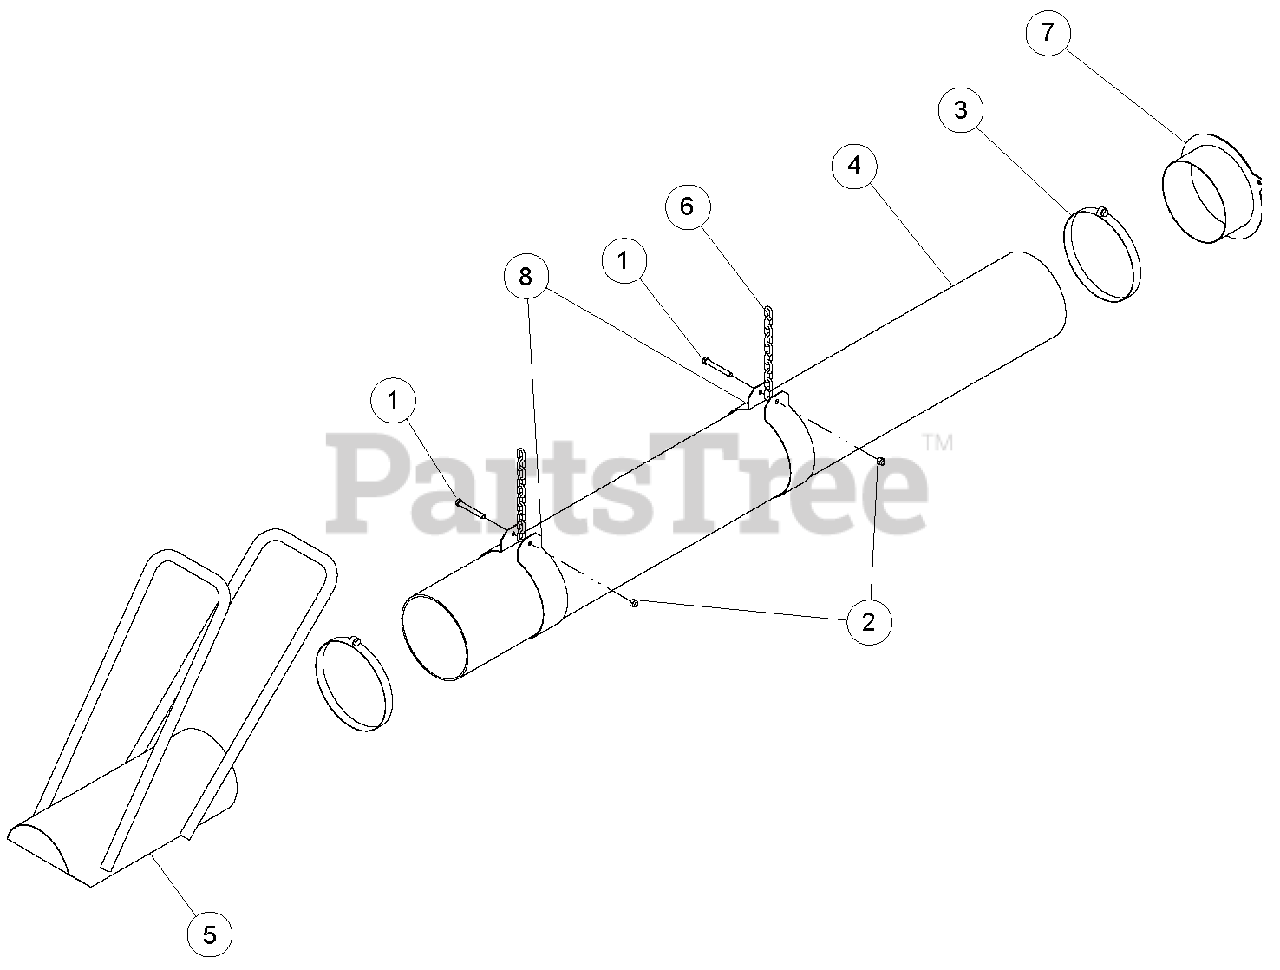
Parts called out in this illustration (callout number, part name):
1	BOLT, 3/8 NC X 3-1/2 HEX HD
2	NUT, 3/8" NYLOCK
3	CLAMP, T-BOLT 8-3/8"
4	HOSE, 8 IN X 12.5 FT INLET
5	WELDMENT, HOSE INLET
6	CHAIN, HOSE SUPPORT
7	WELDMENT, INLET ADAPTER
8	WRAP, HOSE
